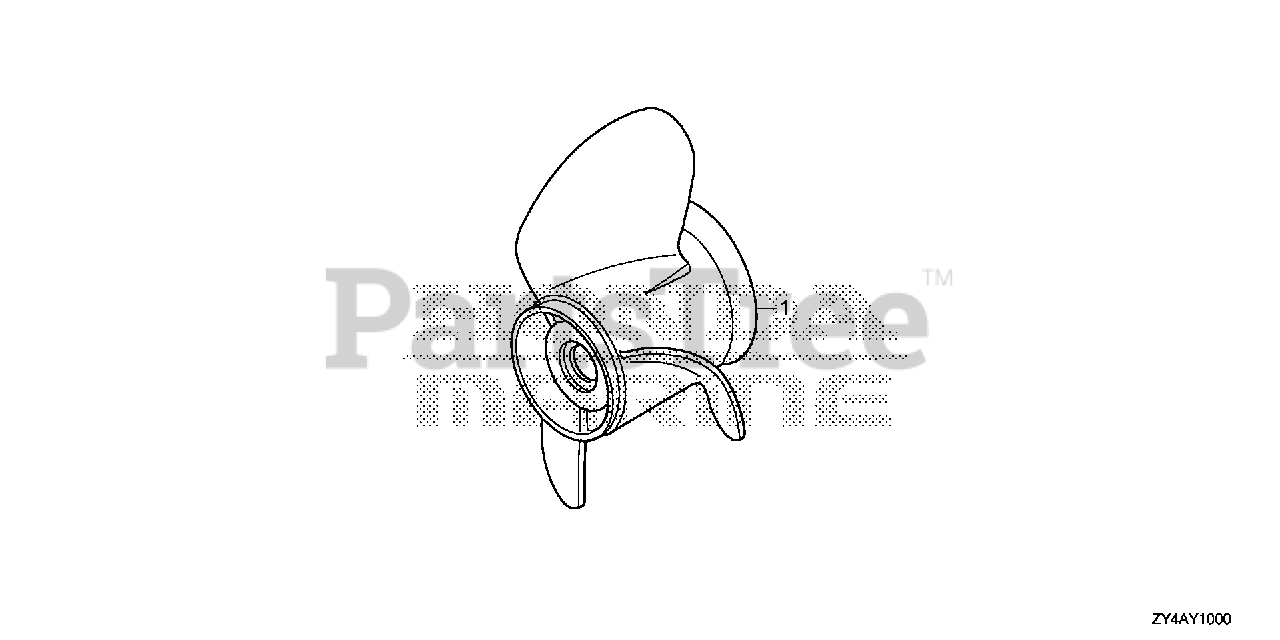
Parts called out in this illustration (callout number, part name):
1	PROPELLER, THREE-BLADE (14-1/2X15) (C/R)
1	PROPELLER, THREE-BLADE (14-1/4X17) (C/R)
1	PROPELLER, THREE-BLADE (14X19) (C/R)
1	PROPELLER, THREE-BLADE (14X21) (C/R)
1	PROPELLER, THREE-BLADE (14-1/2X23) (C/R)
